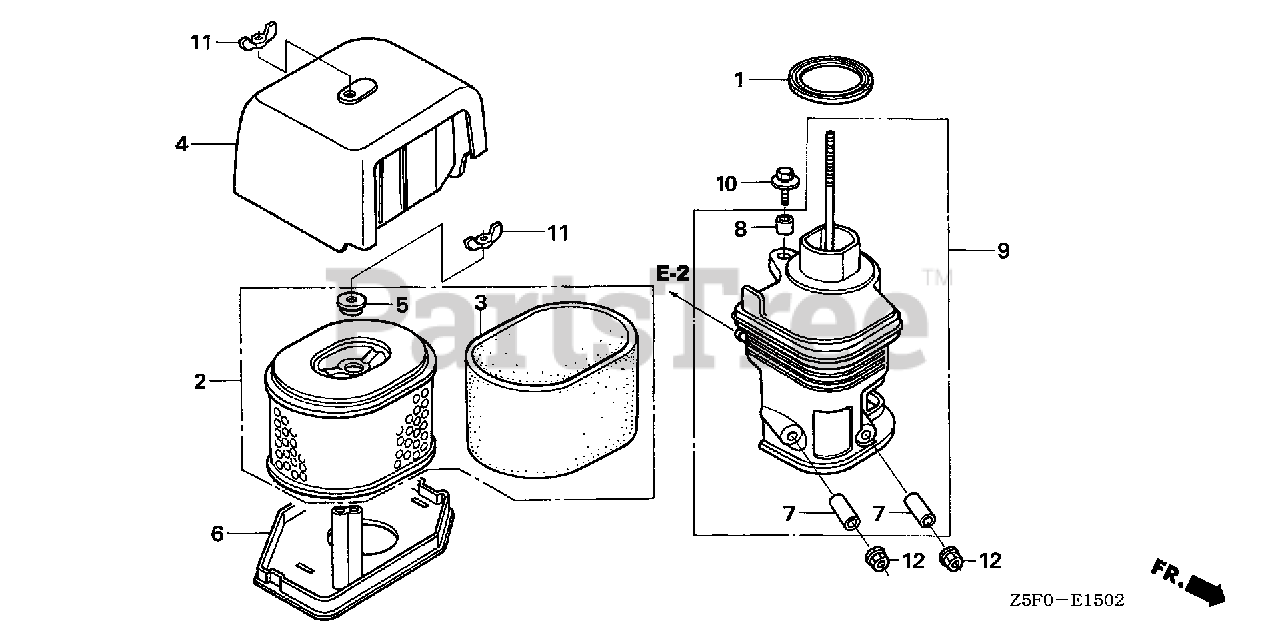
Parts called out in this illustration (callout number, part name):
1	GASKET, ELBOW
2	ELEMENT, AIR CLEANER
3	FILTER (OUTER)
4	COVER, AIR CLEANER (100DB)
5	GROMMET, AIR CLEANER
6	NOSE, MUFFLER
7	COLLAR, AIR CLEANER
8	COLLAR B, AIR CLEANER
9	ELBOW, AIR CLEANER
10	BOLT-WASHER (6X22)
11	WINGNUT, TOOL BOX SETTING
12	NUT, FLANGE (6MM)
